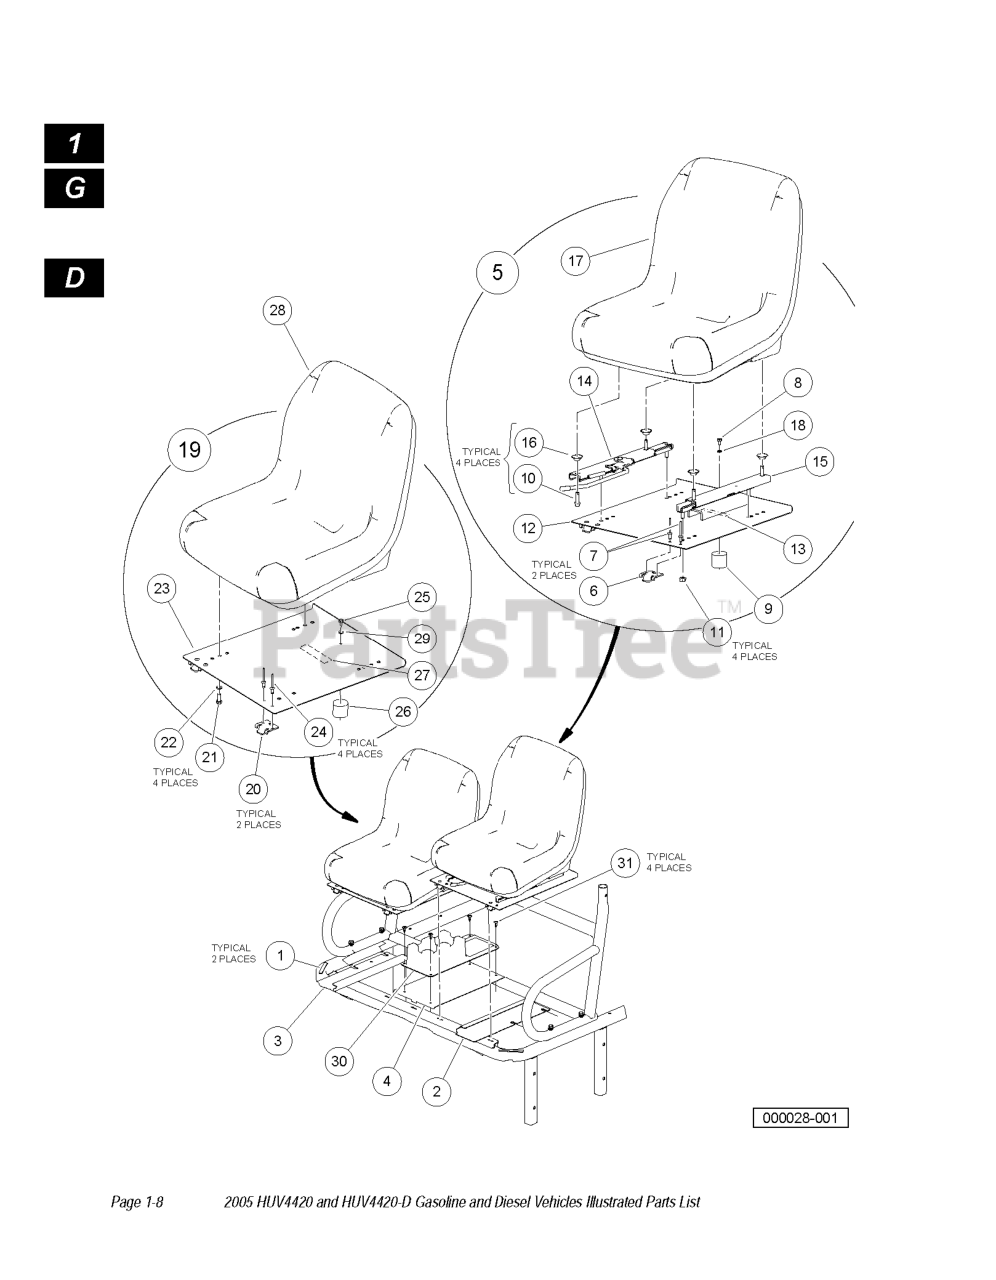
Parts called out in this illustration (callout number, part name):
1	BOX INS.BULK
2	CLOSEOUT, DRIVER SIDE
3	CLOSEOUT, PASSENGER SIDE
4	PAN, CENTER, CLOSEOUT
5	ASM, BUCKET SEAT ADJUSTABLE
6	HINGE PLATE
7	RIVET, 1/4 X .438 BLIND
8	SCREW, 6M-1.00 X 10MM HEX HEAD
9	SEAT HOLDER CUP
10	BOLT - FLANGED HD, M8 X 30.0
11	NUT FLG, M8 X 1.25 MECH DEF
12	PAN, SEAT, DRIVER ASM
13	DECAL, WARNING HOT SURFACE
14	ADJUSTER, FORE/AFT
15	ADJUSTER, SLIDER
16	WASHER, BELL
17	SEAT, BUCKET, GRAY
18	LOCKWASHER, 1/4 HELICAL SPLIT
20	HINGE PLATE
21	SCREW, M8-125 X 22 HEX GR.8.8
23	PAN, SEAT - PASSENGER
24	RIVET, 1/4 X .438 BLIND
25	SCREW, 6M-1.00 X 10MM HEX HEAD
26	SEAT HOLDER CUP
27	DECAL, WARNING HOT SURFACE
28	SEAT, BUCKET, GRAY
29	LOCKWASHER, 1/4 HELICAL SPLIT
30	CONSOLE, CENTER, DRINK HLDR
31	SCREW, TUFLOK PANEL, 1/4
